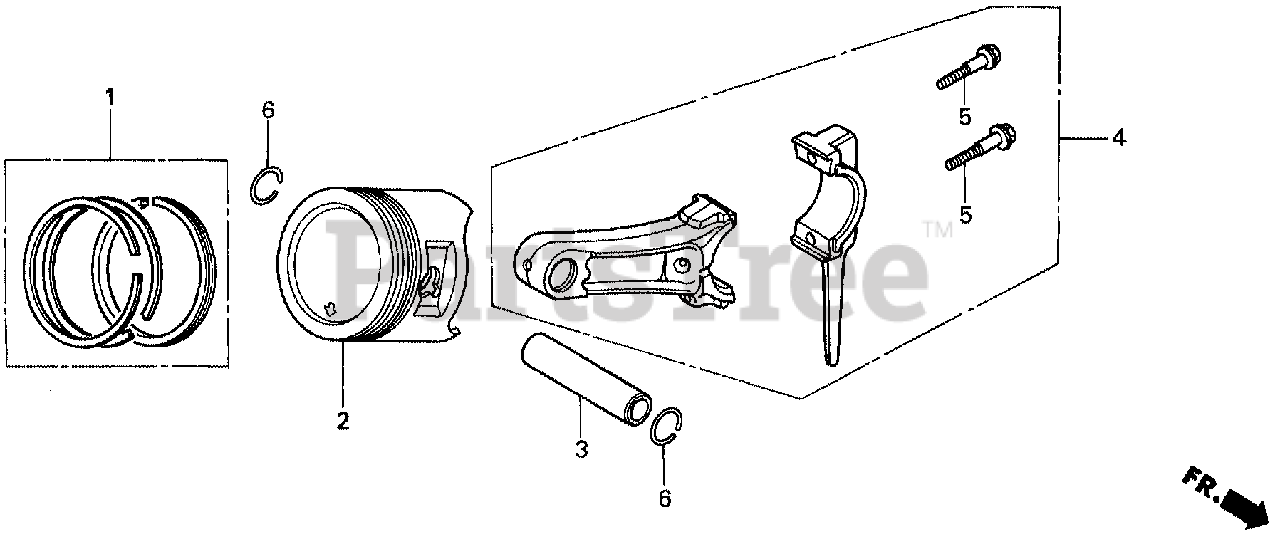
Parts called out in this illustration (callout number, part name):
1	RING SET, PISTON (STD)
1	RING SET, PISTON (OS 0.25)
1	RING SET, PISTON (OS 0.50)
1	RING SET, PISTON (0.75)
2	PISTON (STD)
2	PISTON (OS 0.25)
2	PISTON (OS 0.50)
2	PISTON (0.75)
3	PIN, PISTON
4	ROD ASSY., CONNECTING (US 0.25)
4	ROD ASSY., CONNECTING
5	BOLT, CONNECTING ROD
6	CLIP, PISTON PIN (18MM)
